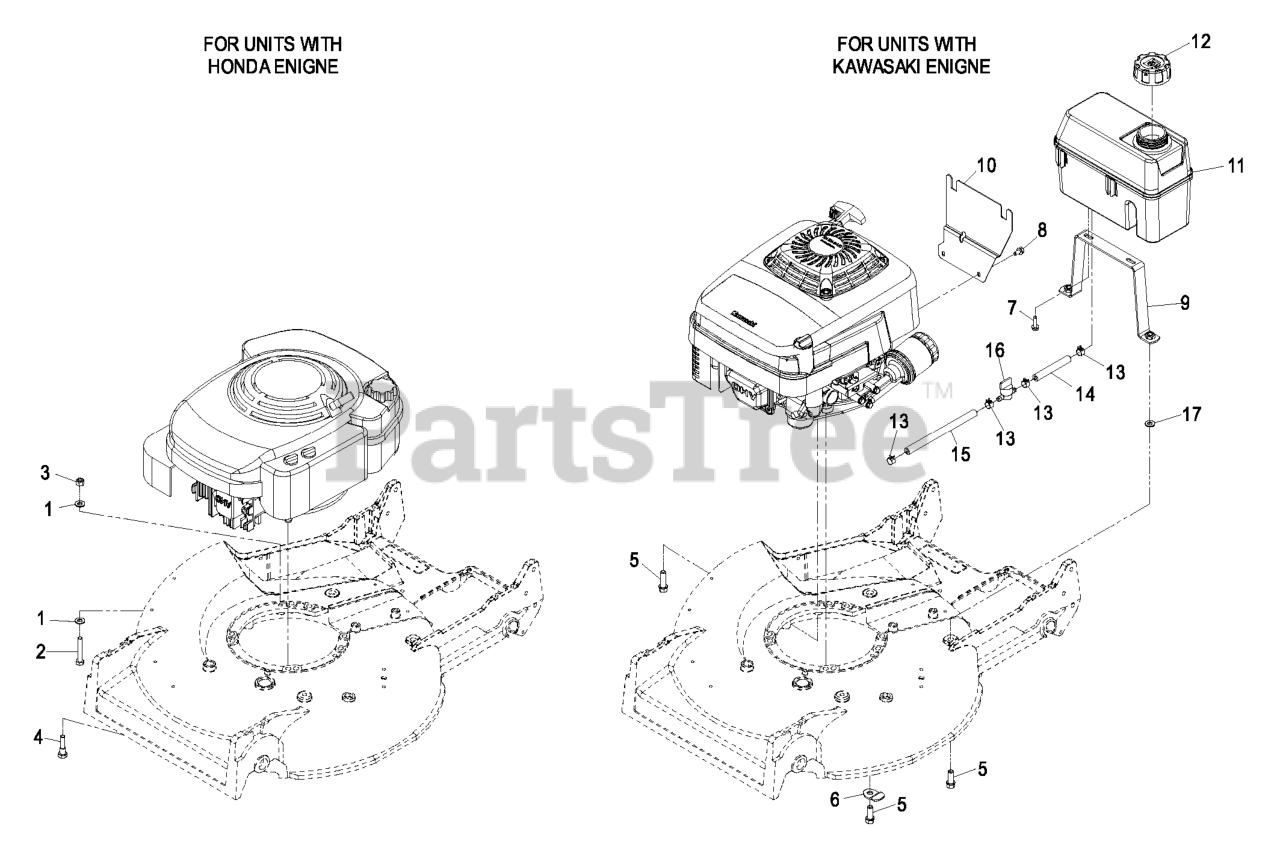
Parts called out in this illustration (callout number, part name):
1	WASHER-PLAIN
2	SCREW-HH
3	NUT-LOCK, NI
4	SCREW-SHOULDER
5	SCREW-TAPTITE
6	SHIELD-RETAINER
7	SCREW-HWH
8	SCREW-HWH
10	BRACKET-TANK
12	CAP-GAS
13	CLAMP-HOSE
16	VALVE-FUEL
17	WASHER-HARDENED
